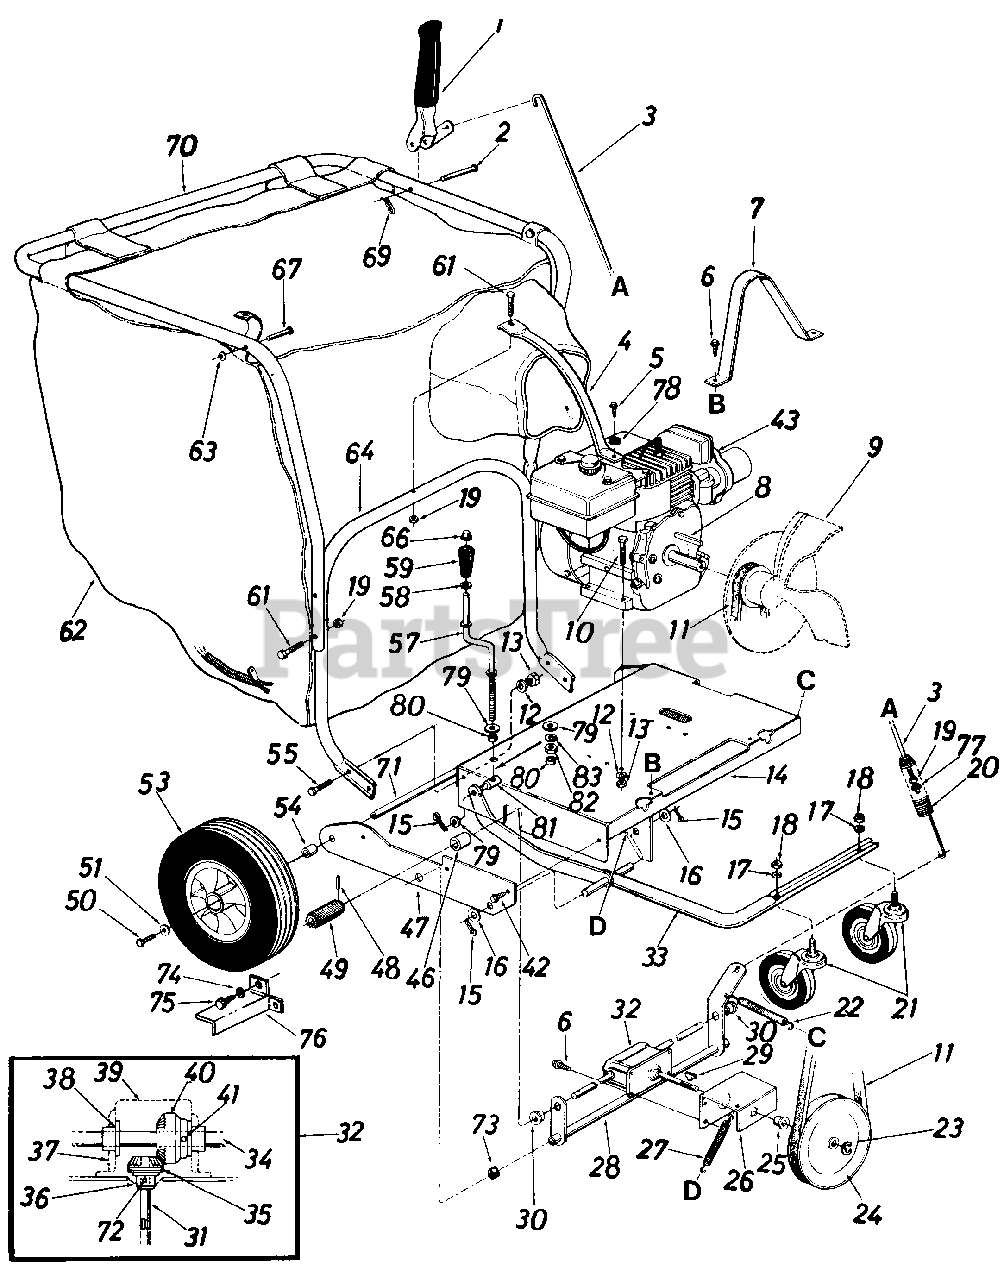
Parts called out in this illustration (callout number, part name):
1	Clutch Grip Ass'y.
2	Clevis Pin .375" Dia. x 1.88"
3	Clutch Rod 32" Lg
4	Handle Brace (Painted)
5	Part of Engine
6	Hex Wash. Hd. AB-Tap Scr. 1/4 x.62" Lg.
11	V -Belt
12	L-Wash. 5/16" I.D.
13	Hex Nut 5/16-18 Thd.
16	Fl-Wash. .63" I.D. x 1.25" O.D.
17	L-Wash. 1/2" I.D.
18	Hex Nut 1/2-13 Thd.
19	Hex Cent. L-Nut 1/4-20 Thd.
20	Extension Spring .78" O.D. x 75" Lg.
21	Swivel Caster Wheel 5" Dia. x 1.25"
22	Extension Spring .38" O.D. x 7.50" Lg.
23	Snap"E"-Ring.50" Dia. Shaft
24	"V"-Pulley 5/8" x 6.50" O.D.
25	Flange Bearing .502" I.D.
28	Clutch Bracket Assy.
29	#2 Woodruff Key 8/32" Dia. x .81" Lg.
30	Hex Flange Bearing Bronze .625" I.D.
31	Pinion Shaft .50" Dia. x 5"
32	Gear Box Ass y. Comp.
35	Bevel Gear .50" I.D. x 14 Teeth
36	Flange Bearing .503" I.D.
37	Gear Box
38	Flange Bearing .630" I.D.
39	Gear Box Cover
40	Bevel Gear .62" I.D. x 28 Teeth
41	Spring Pin Spiral 3/16" Dia. x 1.25" Lg.
42	Hex Wash. Hd. AB-Tap Scr. 5/16" x.75" Lg.
43	Engine
46	Spacer.63" I.D. x .88" O.D. x .56" Lg.
49	Drive Pinion
50	Hex Locking Bolt 5/16-24 x .62" Lg.
51	Fl-Wash. .34" I.D. x .87" O.D.
53	Wheel Ass'y. Comp. 12 x 3" (Incl. Ball Bearings)
54	Spacer .63" I.D. x 1.0" O.D. x .941" Lg.
55	Hex Bolt 5/16-18 x .751' Lg.
57	Height Adjustment Crank
58	Fl-Wash. .385" I.D. x .62n O.D.
59	Crank Knob
61	Hex Bolt 1/4-20 x 1.75" Lg.
62	Vacuum Bag-Felt
63	Push Speed Nut .25" Dia. Stud
66	Push Nut 3/8" Dia.
67	Stud Pin .250" Dia. x 1.75
69	Internal Cotter Pin 3/8" Dia.
70	Upper Handle (Painted)
71	Rear Axle
72	Spring Roll Pin 5/32 Dia. x 1.12
73	Spacer .82 I.D. x 1.0" O.D. x .305 Lg
74	L-Wash. .265" I.D.
75	Hex Self-Tap Scr. 1/4" x 3/8" Lg
78	Belleville Washer
79	Fl-Wash. .35" I.D. x.87" O.D.
80	Spacer .38" I.D. x .50" O.D. x .18n Lg.
81	Ferrule 3/8-8 x .38 Dia.
82	Hex Nut 3/8-8 Thd.
83	L-Wash. 3/8" I.D.
